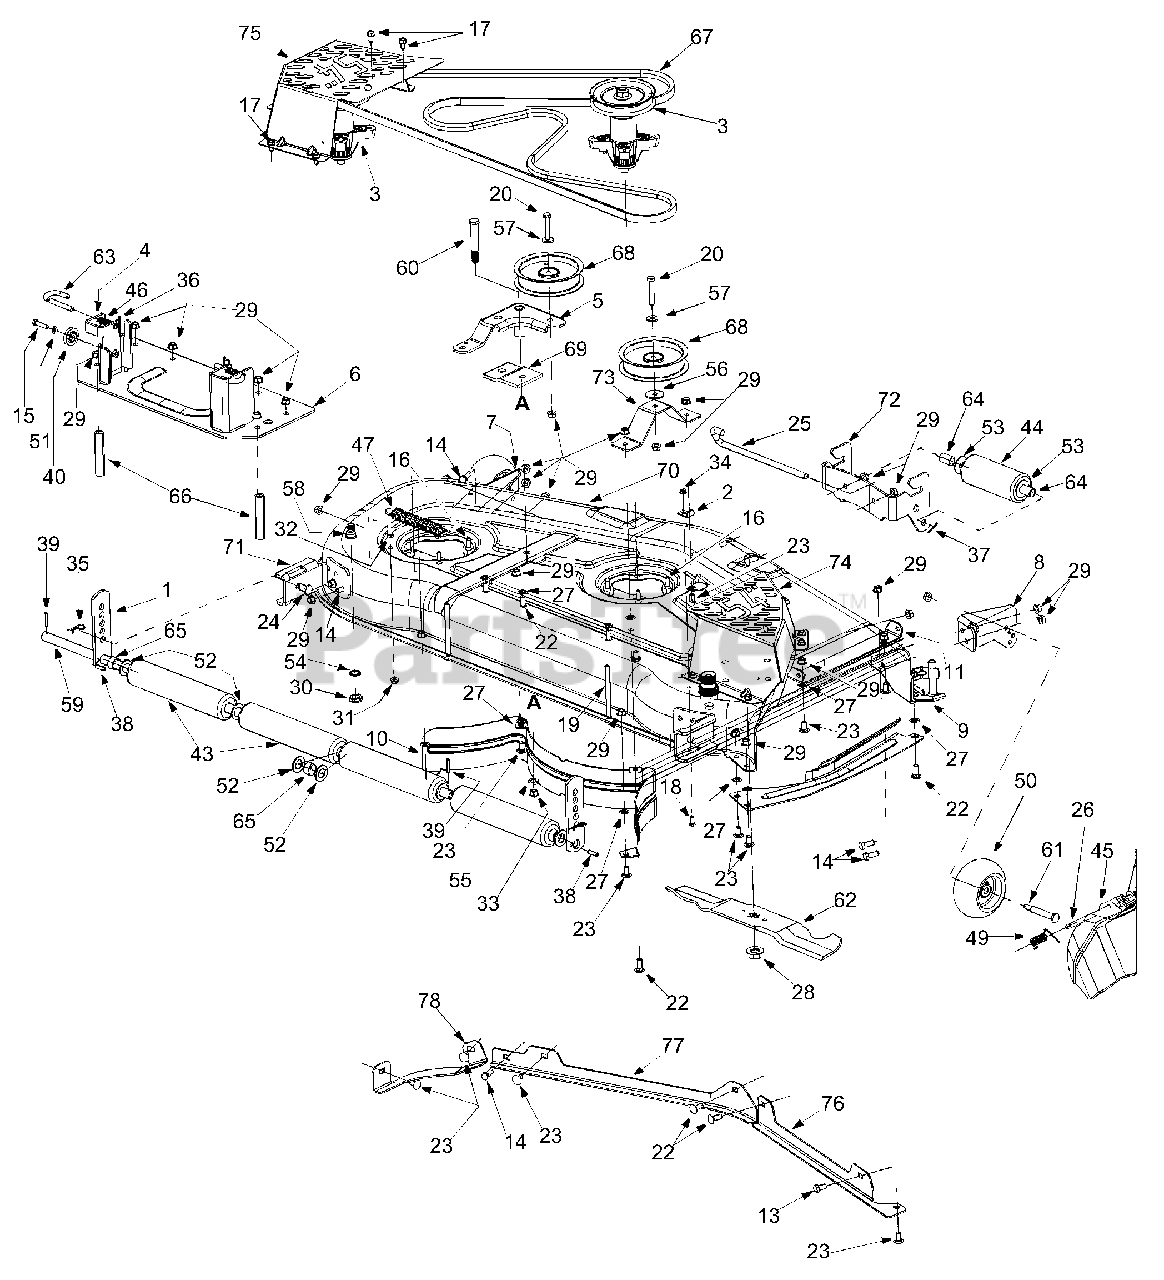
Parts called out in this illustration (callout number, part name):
2	Bracket, Hook, Retainer
3	Spindle Assembly, Pulley, 5.39 Dia x .5625
11	Bracket
12	Guard, Finger
13	Hex Screw 3/8-16 x 0.75
14	Hex Screw 3/8-16 x 1.0
15	Hex Screw, 5/16-18 x 1.25
16	Screw, Self-tapping, 5/16-18 x 1.000
17	Screw, AB, 5/16-12 x 0.75
18	Hex Screw, 1/4-20 x .620
19	Screw, Carriage, 3/8-16 x 5.00
20	Hex Screw, 3/8-16 x 2.25
21	Hex Screw, 5/16-18 x 2.25
22	Bolt, Carriage, 3/8-16 x 1.0
23	Short Neck Carriage Bolt 3/8-16 x .75
24	Pin, Clevis, .50 Dia x .78
25	Pin, Roller, .5" Dia x 10.06
26	Pin, Hinge, Dia .375 x 14.06
27	Push Nut Retainer
28	Nut, Hex Flange, 5/8-18
29	Nut, Flange Lock, 3/8-16
30	Hex Nut M16
31	Nut, Flange Lock, 5/16-18, Gr5
32	Nut, Hex, 5/16-18, Gr5
33	Nut, Hex Lock, 1/2-13
34	Nut, 1/4-20, Hexflg, Lock
35	Pin, Click, .092 x 1.64
36	Pin, Cotter, 1/8 x 1.25
37	Pin, Cotter, 3/32 x 1.25
38	Pin, Sprg, 1/4 Dia x 1.00
39	Pin, Spring, 3/16 x 1.25
40	Adjustment, Deck, Gear
41	Water Nozzle Adaptor
43	Roller, Deck
44	Front Roller
45	Deflector, Chute
46	Spring, Compression, .406 x .531 x 1.75
47	Spring, Extension, .94 Dia x 6.74
48	Spring, Extension, 1.15 Dia x 5.99
49	Torsion Spring .44 I.d. x 2.10
50	Deck Wheel, 5" Dia.
51	Lock Washer
52	Flat Washer, .812 ID x 1.38 OD x .1
53	Flat Washer, .51 ID x 1.5 OD x .07
54	Lock Washer
55	Washer, Lock, 1/2 , Regular Duty
56	Flat Washer .406 ID X 1.5 x 11ga
57	Washer, Flat .38 ID x.93 OD x.110
58	Water Nozzle: Deck Wash-Out System
59	Roller Shaft
60	Shoulder Screw
61	Shoulder Screw, 1/2 Dia x 2.50
62	Blade, 18.50"
63	Deck Release Handle Rod, .375 Dia
64	Spacer .550 ID x .755 OD x 1.1
65	Spacer, .82 ID x 1.00 OD x .53
66	Spacer, .405 x .75 x 3.875
67	Belt, V-Type, B Section
68	Pulley, Idler, 5.0 Dia.
78	LH Extension Skirt
